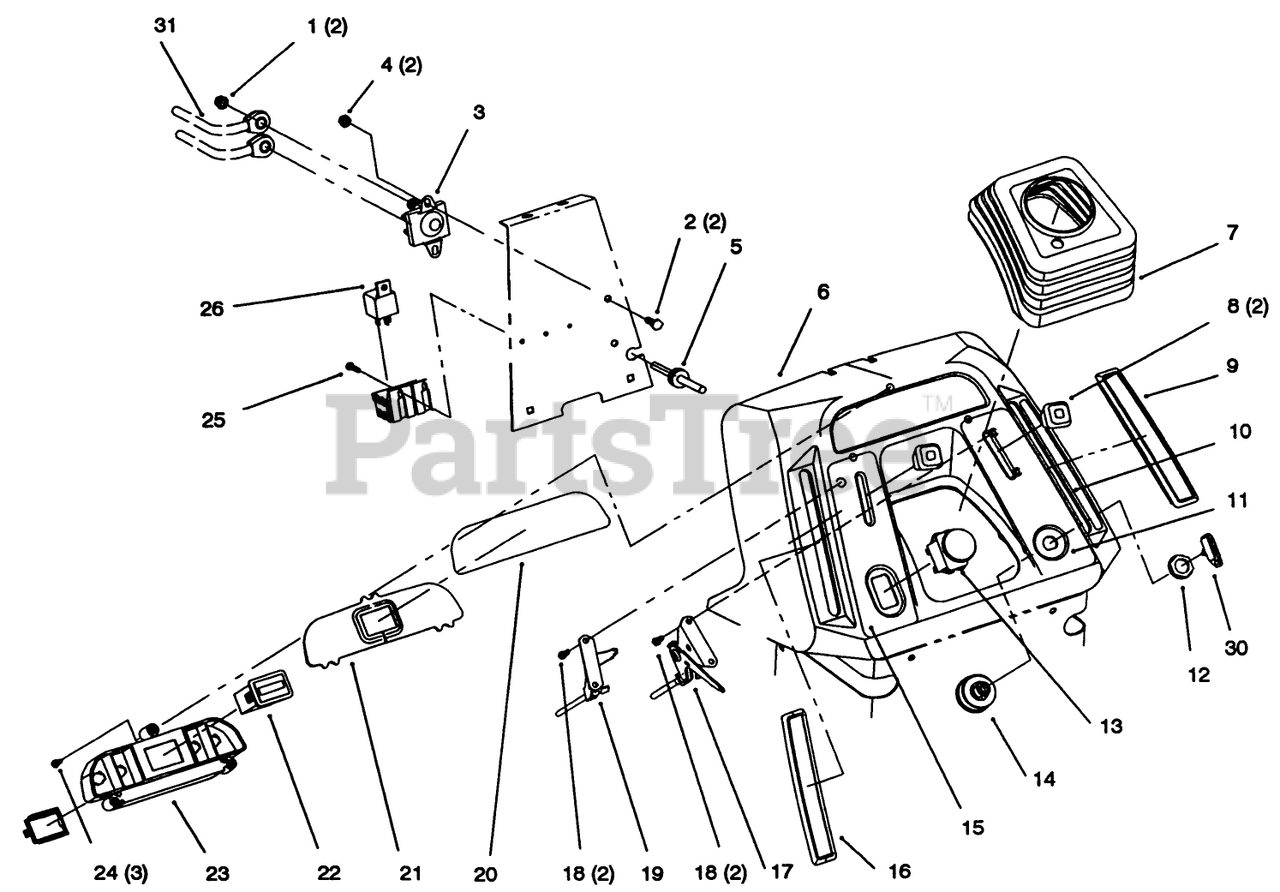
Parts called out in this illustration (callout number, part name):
1	NUT-KEPS
2	SCREW-HH
4	NUT-LOCK, NI
5	GROMMET-RUBBER
7	BOOT-STEERING
9	COVER-SLOT, RH
10	DECAL - SHIFT
11	DECAL-THROTTLE, IGNITION
14	SWITCH-IGNITION
15	DECAL-PTO / CHOKE
15	DECAL - DASH PTO/CHOKE
16	COVER-SLOT, LH
17	CONTROL-THROTTLE
17	CONTROL-THROTTLE (TWIN)
19	CONTROL-CHOKE
19	CONTROL-CHOKE (TWIN)
21	LENS-DASH
23	HOUSING-LIGHT, INDICATOR
24	SCREW-PPH
25	SCREW-PPHTF
26	RELAY
30	KEY-IGNITION
31	WIRE-21 INCH
